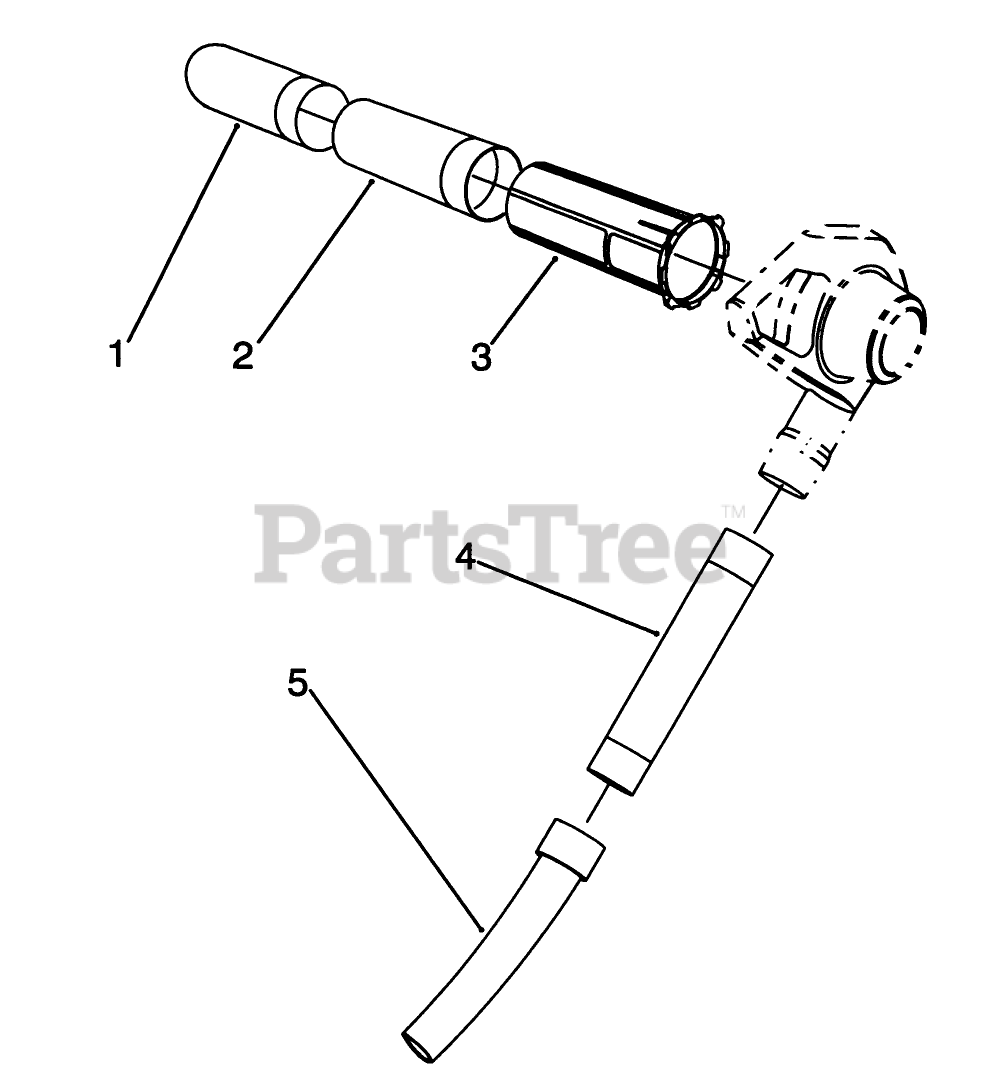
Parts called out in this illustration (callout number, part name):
1	LOWER VAC TUBE
2	MIDDLE VAC TUBE
5	MID BL-DISCHARGE TUBE
